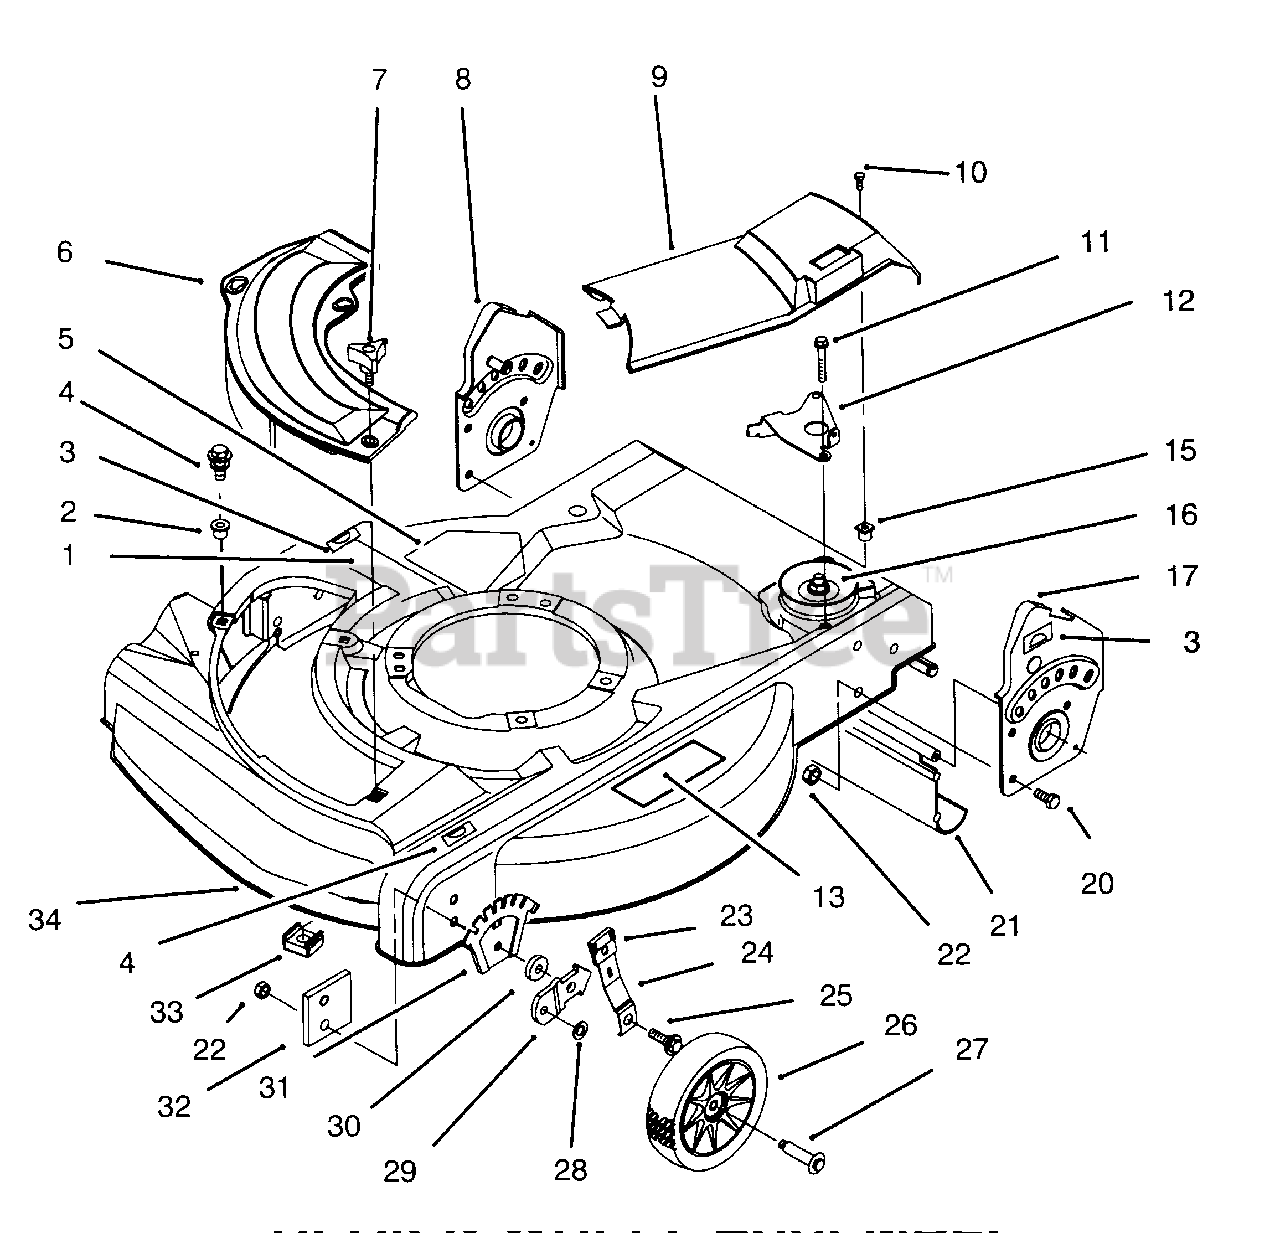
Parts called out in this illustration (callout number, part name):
1	Decal-Danger
2	Grommet-Plastic
3	Decal-H.O.C. L.H.
4	Screw-Thread Forming
5	Decal-Danger
6	Plate-Cover, Mulch
7	Knob
8	Handle Bracket Ass'y-R
9	Cover-Drive
11	Screw-Thread Forming
12	Guide-Transmission
13	Decal-Warning
15	Grommet-Shroud Mtg.
16	Gear Case Ass'y
17	Handle Bracket Ass'y-L.H.
20	Screw-Hex. Hd.
21	Shield-Trailing
23	Knob-H.O.C.
24	Arm-Spring
25	Bolt-Shoulder
26	Wheel Assembly-6"
27	Bolt-Wheel
29	Bracket-H.O.C.
31	Plate H.O.C.
32	Plate-Baffle
33	Nut-Cage
34	Housing & Baffle Ass'y (Incl. Ref. # 1-5, & 13)
